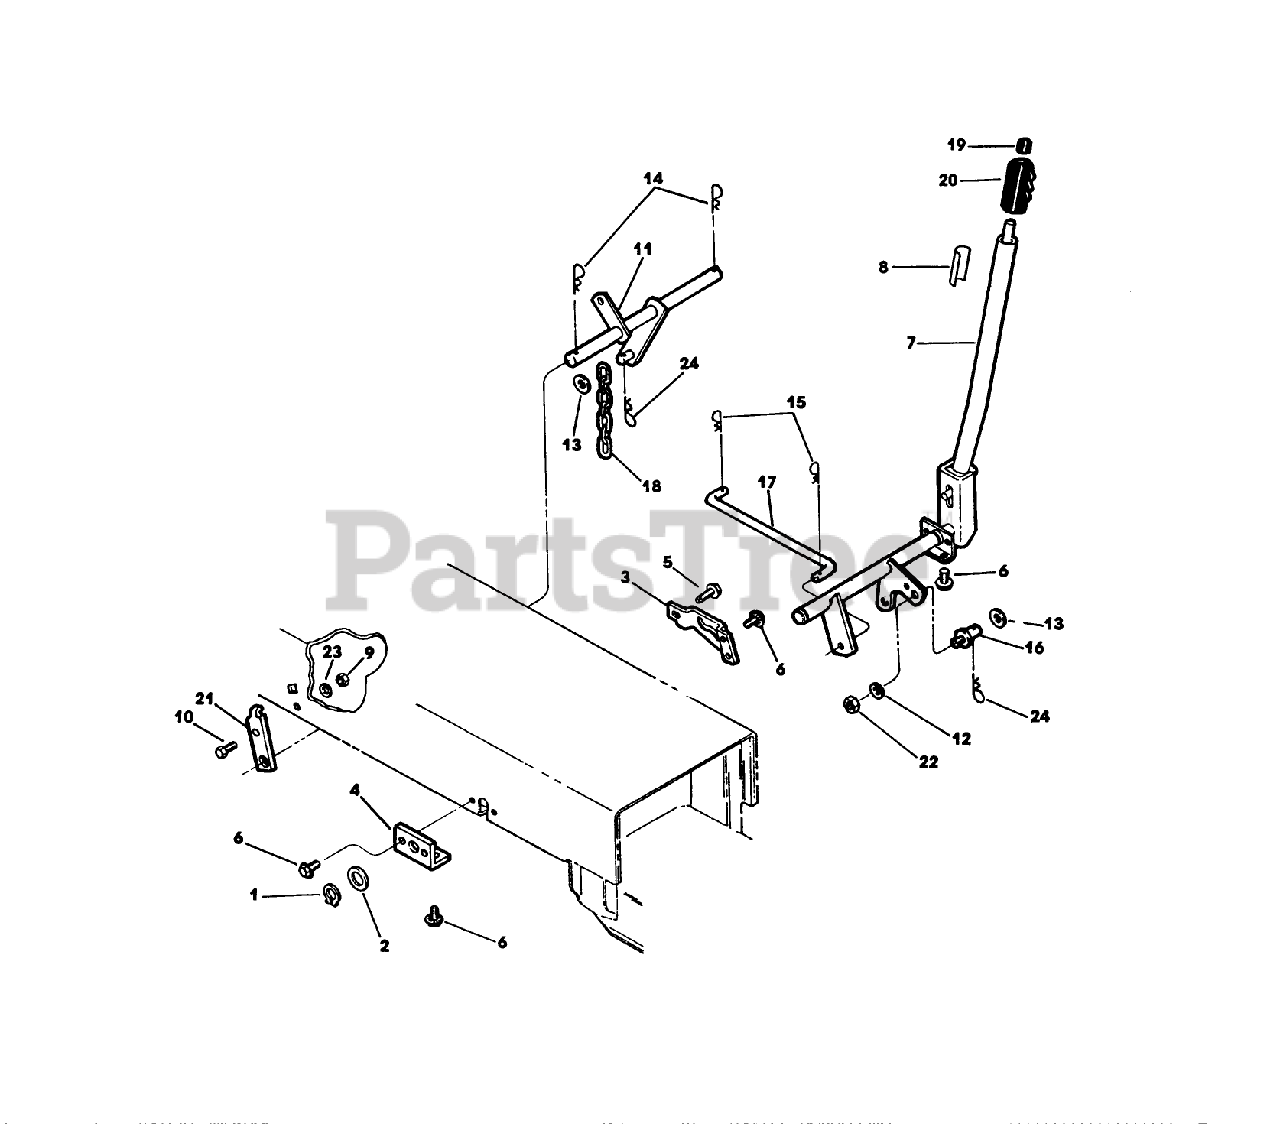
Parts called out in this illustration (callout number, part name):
1	RING-RETAINING
2	WASHER
8	STICKER-LIFT
9	NUT SS
11	LIFT ARM WELDMENT
12	WASHER
15	PIN-HAIR
19	TIP-ROD
21	ARM-MOWER LIFT
22	NUT
24	PIN-HAIR
